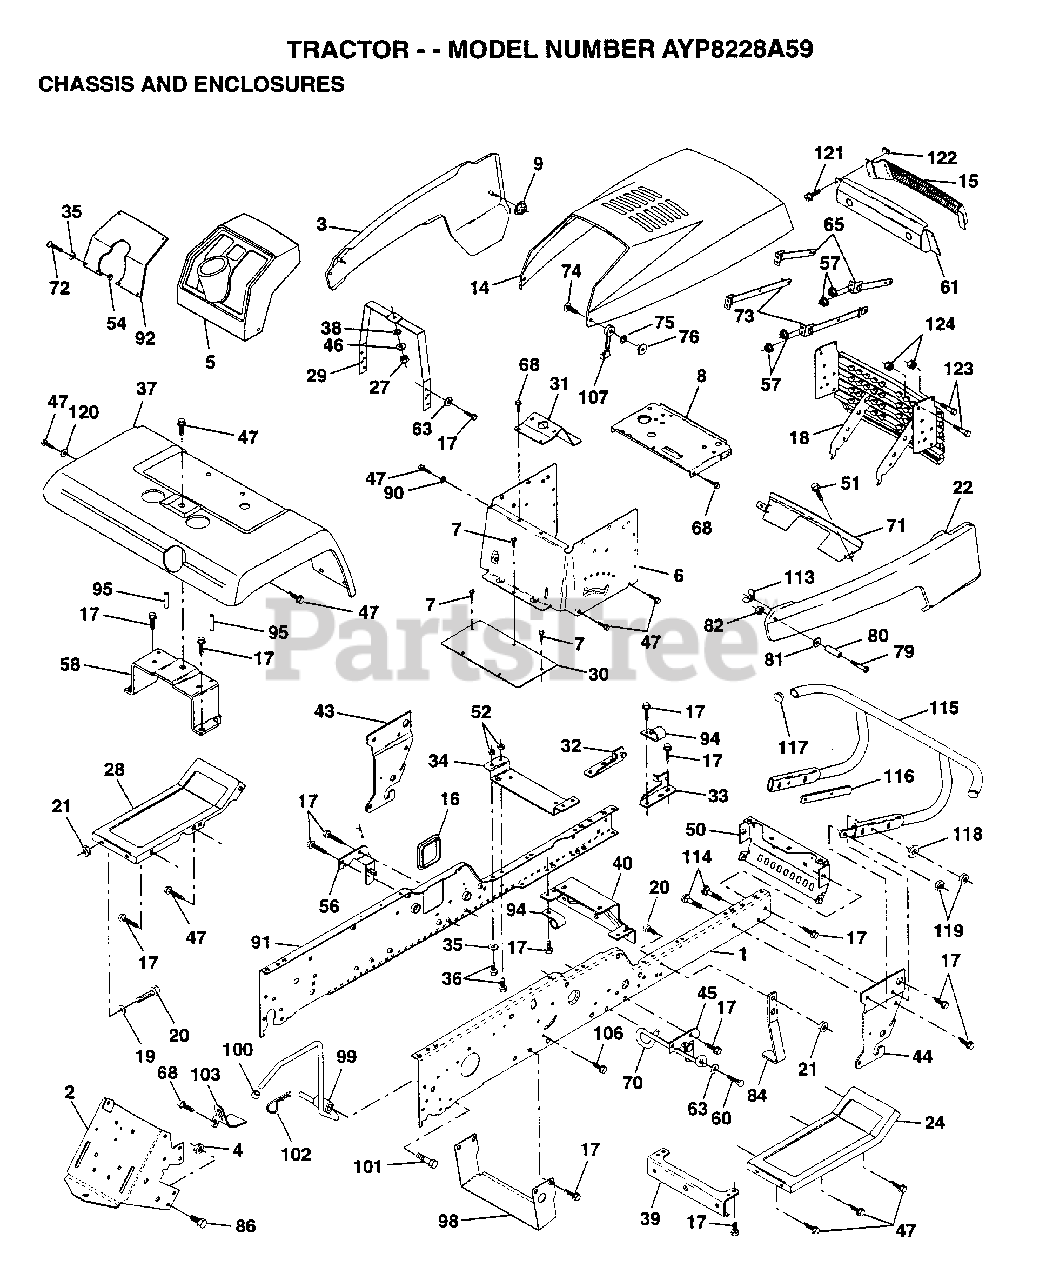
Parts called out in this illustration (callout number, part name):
2	DRAWBAR GT
3	PANEL SD LH YT/GT
4	NUT.7/16
5	DASHBOARD BLACK
6	DASH.1PC.LOWER
7	SCREW
8	SUPPORT.DASH.BTRY
9	PAL NUT LT
15	LENS LT
16	COVER ACCESS
17	SCREW
19	WASHER
20	BOLT
22	PANEL SD RH YT/GT
24	FOOTREST.RH.LT/GT
28	FOOTREST.LH.LT/GT
29	DASH.SUPT.YP/HUSQ
30	SADDLE.HYDRO.95
31	BRAKET.SUPT.STEER
32	BRACKET ASM FRAME
33	BRACKET ASM FRAME
34	BRACKET.ENG.SUPT.
35	WASHER
36	BOLT
37	FENDER.PNT.
38	LOCKWASHER
39	BRACKET.AXLE.FRT.
43	BRACKET.SUS.FT.LH
44	BRACKET.SUS.FT.RH
46	WASHER PM
47	SCREW LT
50	BRACKET.CHASSIS.
51	SCREW CRT
57	NUT
58	BRKT.ASM.FENDER
60	SCREW
63	WASHER
68	SCREW LT
70	GUIDE.BELT.MID.SP
72	SCREW
75	SCREW
75	LOCKWASHER
76	WELDNUT
79	SCREW
80	SPACER LT
81	WASHER
84	STOP.OVER.CENTER
86	BOLT
90	LOCKWASHER
92	PLATE SLKSCR YP
94	CLIP GTV
95	NUT-PUSH YT
98	BRACKET SKID CHAS
99	ROD BYPASS
101	SCREW LT
102	RETAINER M
103	LOCK BYPASS BRKT
107	HOOD LATCH T
114	BOLT.3/8-14X1.25
115	BUMPER.ASM.W/PY
116	BRACKET.EXT.BUMP.
117	PLUG.PLASTIC
118	WASHER
120	WASHER HYT
122	"""J"" FASTENER LT"
124	NUT
